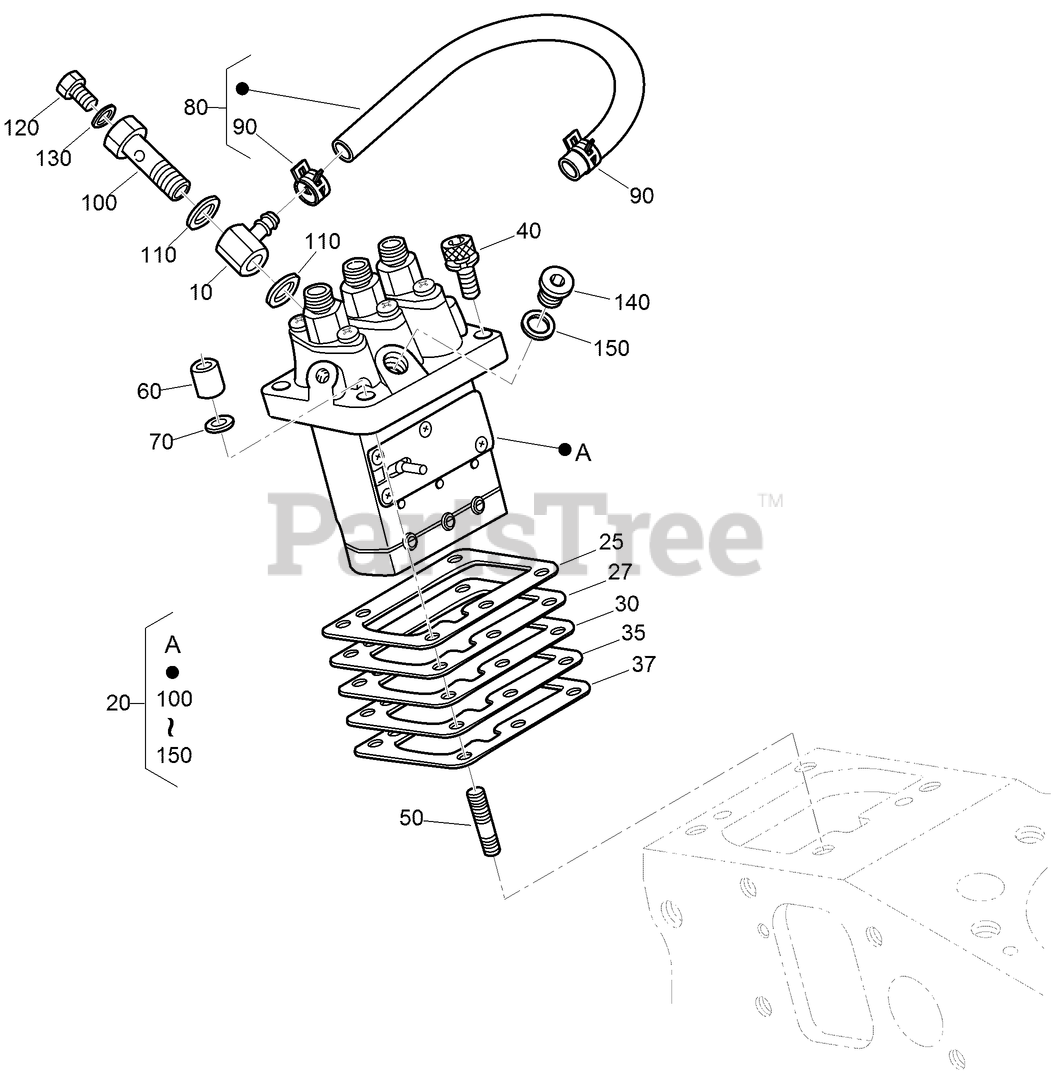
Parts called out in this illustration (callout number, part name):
10	JOINT-EYE
20	INJECTION PUMP ASM
25	SHIM-INJECTION (0.175MM)
27	SHIM-INJECTION (0.20MM)
30	SHIM-INJECTION (0.25MM)
35	SHIM-INJECTION (0.30MM)
37	SHIM-INJECTION (0.35MM)
40	BOLT-HEX SOC HD
60	NUT-CAP
70	WASHER-SPRING
80	FUEL PIPE ASM
90	CLIP-PIPE
100	SCREW-HOLLOW
110	GASKET
120	SCREW
130	GASKET
150	GASKET
